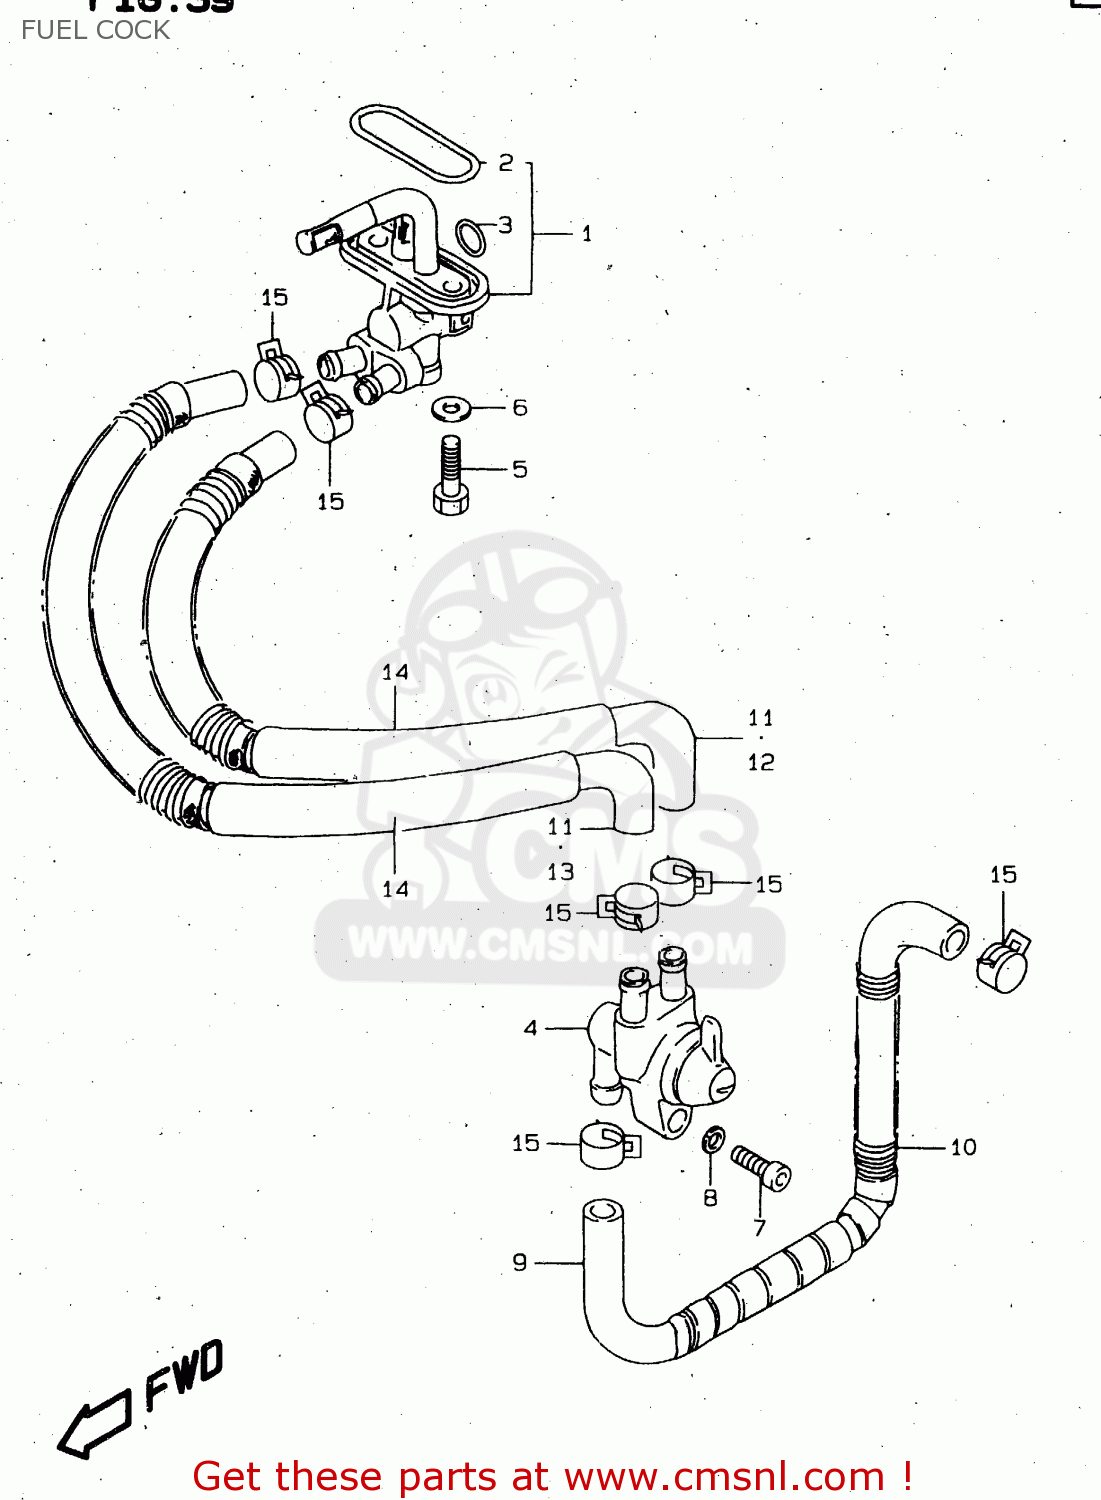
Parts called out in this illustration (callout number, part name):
1	COCK ASSY,FUEL
2	O RING,FUEL COCK
3	O RING,LEVER
4	COCK ASSY,FUEL
5	BOLT(6X20)
6	GASKET(5.8X13X1.2) (NAS)
7	BOLT
8	LOCK,WASHER
9	HOSE COMP,FUEL PUMP &
10	SPRING
11	HOSE,FUEL
12	HOSE,FUEL
13	HOSE,FUEL NO.2
14	TUBE,FUEL HOSE
15	CLIP
